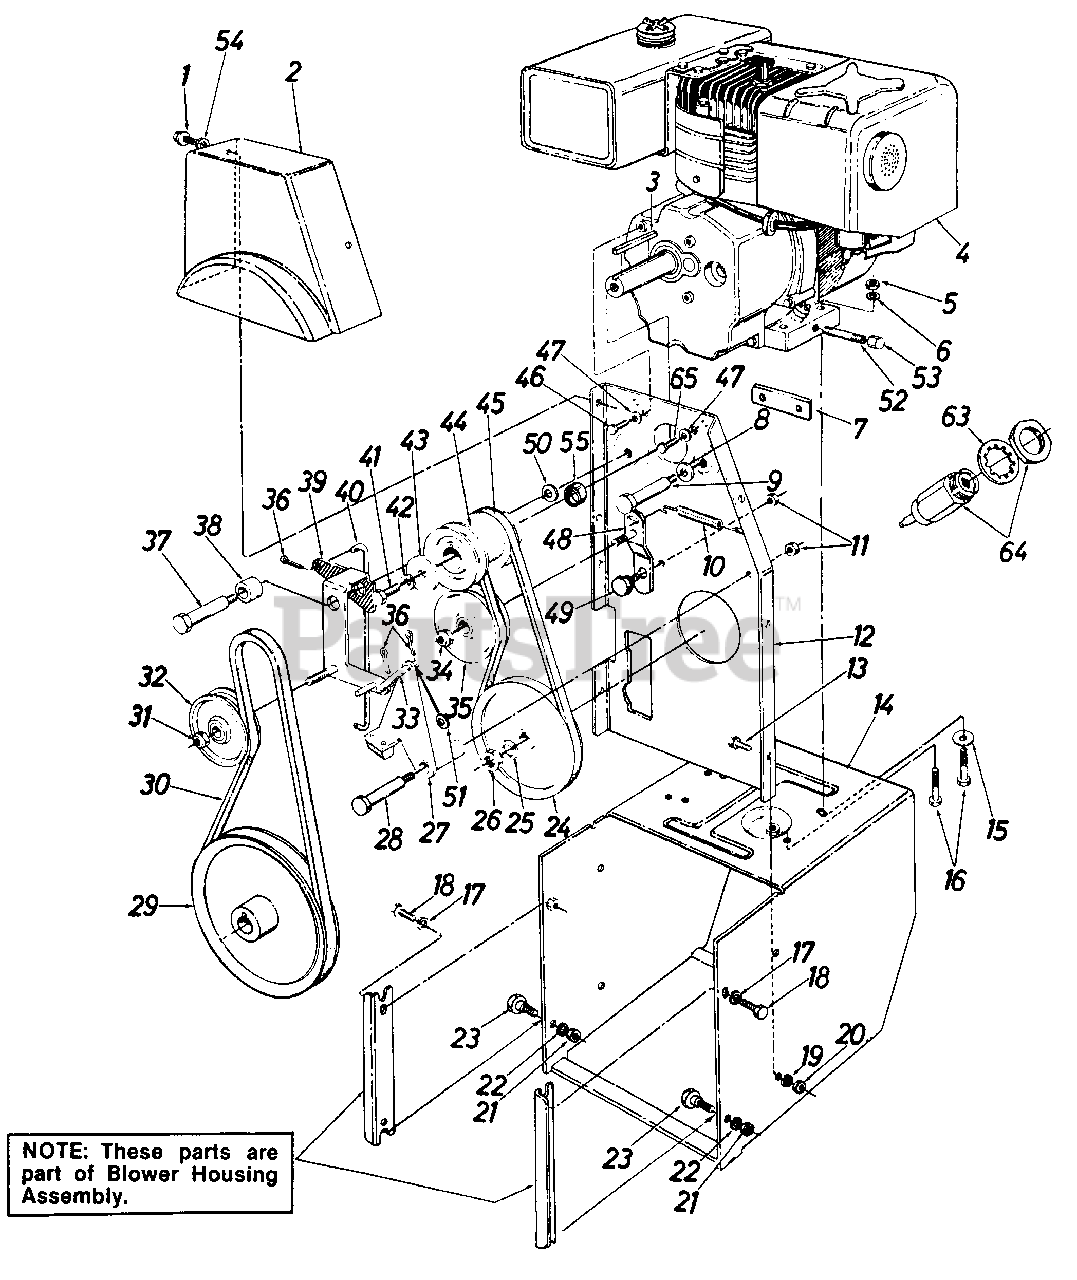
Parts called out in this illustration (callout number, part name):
1	Hex Wash. Self-Tap Scr. 5/16-24 x .50" Lg.
2	Belt Cover
3	Ssq. Key 1/4" X 1.50" Lg.
4	Engine
5	Hex Nut 5/16-18 Thd.*
6	L-Wash. 5/16" Scr.*
7	Engine Spacer Plate
8	Bell-Wash. .40 I.D. x .88 O.D.
9	Shld. Scr. .498" Dia. x 3.00" Lg.
10	Ext. Spring .38 O.D. x 3.18" Lg.
11	Hex Cent. L-Nut 3/8-16 Thd.
12	Engine Brkt. Ass'y.
13	Hex Sems Scr. 5/16-18 x .75" Lg.*
14	Frame Ass'y.
15	Fl-Wash. .345 I.D. x .75 O.D. x .060
16	Hex Scr. 5/16-18 x 1.75" Lg. *
17	L-Wash. 3/8" Scr. H.D.
18	Pilot Scr. 3/8-16 x .88" Lg.
19	L-Wash. 5/16" Scr.*
20	Hex Nut 5/16-18 Thd.*
21	Hex Nut 3/8-16 Thd.*
22	L-Wash. 5/8" Scr. H.D.
23	Shld. Scr. .498" Dia. x .340" Lg.
24	V-Puiley .628 I.D. x 7.50 O.D.
25	L-Wash. for 5/8" Scr.*
26	Hex Ins. Jam L-Nut 5/8-18 Thd.
27	Brake Brkt. Ass'y.
28	Shld. Scr. .498" Dia. x 2.00" Lg.
29	V-Pulley .875 I.D. x 10.12 O.D.
30	"V"-Belt 1/2" x 45.0" Lg.
31	Hex Ins. Jam L-Nut 3/8-24 Thd.
32	Fl-ldler w/Flanges 3.0 O.D.
33	Brake Linkage Ass'y.
34	Hex Ins. Jam L-Nut 3/8-24 Thd.
35	3.0" O.D. Fl-ldler w/Flanges
36	Int. Cot. Pin 5/16" Dia.
37	Shld. Scr. .625 Dia. x 2.750" Lg.
38	Spacer .75 O.D. x 1.00" Lg.
41	Hex Bolt 3/8-24 x 1.25" Lg.
42	L-Wash. 3/8" Scr. H.D.
43	Fl-Wash.
44	Engine Pulley-Double Groove
45	"V"-Belt 3/8 x 35.5 Lg.
46	Hex Bolt 5/16-24 x 1.0" Lg.*
47	Bell-Wash. .345 I.D. x .88 O.D. x .060
48	Drive Idler Brkt. Ass'y.
49	Shld. Scr.-.625" Dia. x .170" Lg.
50	Bell-Wash. .40 I.D. x 1.12 O.D.
51	Fl-Wash. .34 I.D. x .750 O.D. x .05
52	Pipe Nipple-3/8-18 x 3.0" Lg.
53	Cap Oil Drain
54	Fl-Wash. .340 I.D. x .62 O.D. x .62
55	Spacer 1.0" I.D. x 1.32" O.D. x .4 "
63	L-Wash. 518" I.D.
64	Ignition Switch
65	Hex Wash. Hd. Self-Tap Scr 5/16-24 x .50" Lg.
